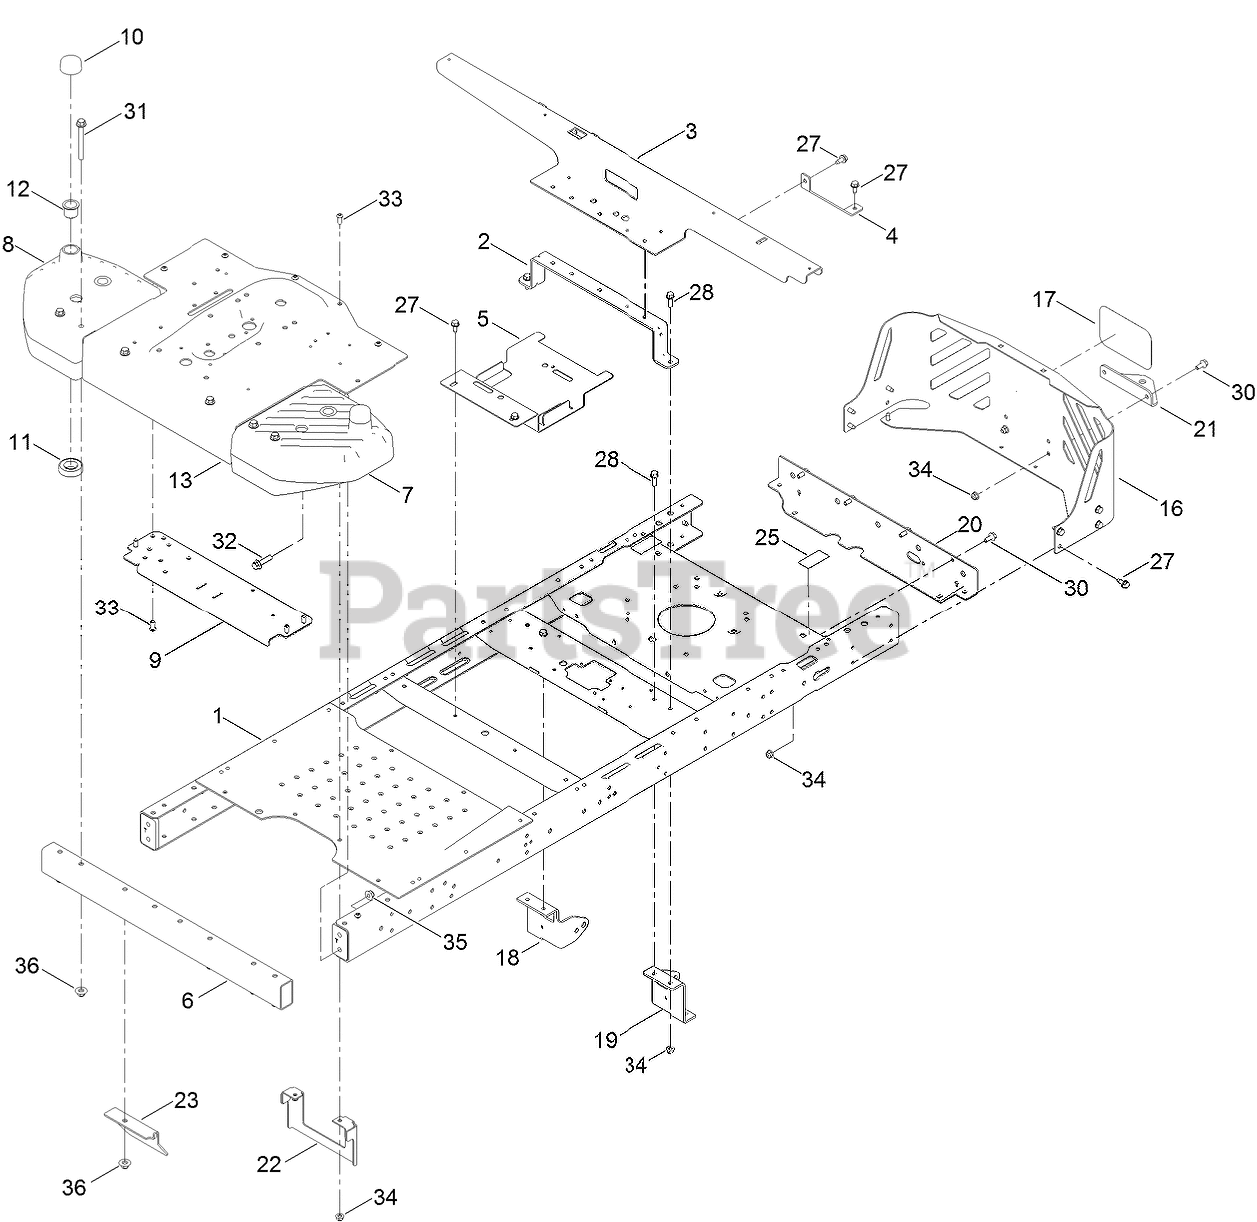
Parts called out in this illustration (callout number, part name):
1	FRAME ASM (WIDE)
2	BRACE-SEAT, REAR (WIDE)
3	SUPPORT-POD, WIDE
4	SUPPORT-TANK, REAR
5	BRACKET-BATTERY
6	TUBE-FRONT, WIDE
7	HOUSING-SPINDLE, LH
8	HOUSING-SPINDLE, RH
9	PLATE-BRIDGE, WIDE
10	CAP-CASTER
11	BEARING-BALL
12	BUSHING-PIVOT
13	PAN-STEER, FRONT
16	GUARD-ENGINE, WIDE
17	DECAL
18	MOUNT-HYDRO, FRONT (RIGHT)
19	MOUNT-HYDRO, FRONT (LEFT)
20	CROSSMEMBER-REAR, WIDE
21	BRACKET-HITCH
22	BRACKET-UPSTOP
23	GUARD-FRONT
25	DECAL-BYPASS
27	SCREW-HWHTF
28	SCREW-HHF
30	SCREW-HHF
31	SCREW-HHF
32	SCREW-HHF
33	SCREW-HSBH
34	NUT-HF, NI
35	NUT-HF, NI
36	NUT-FLANGE, NI
